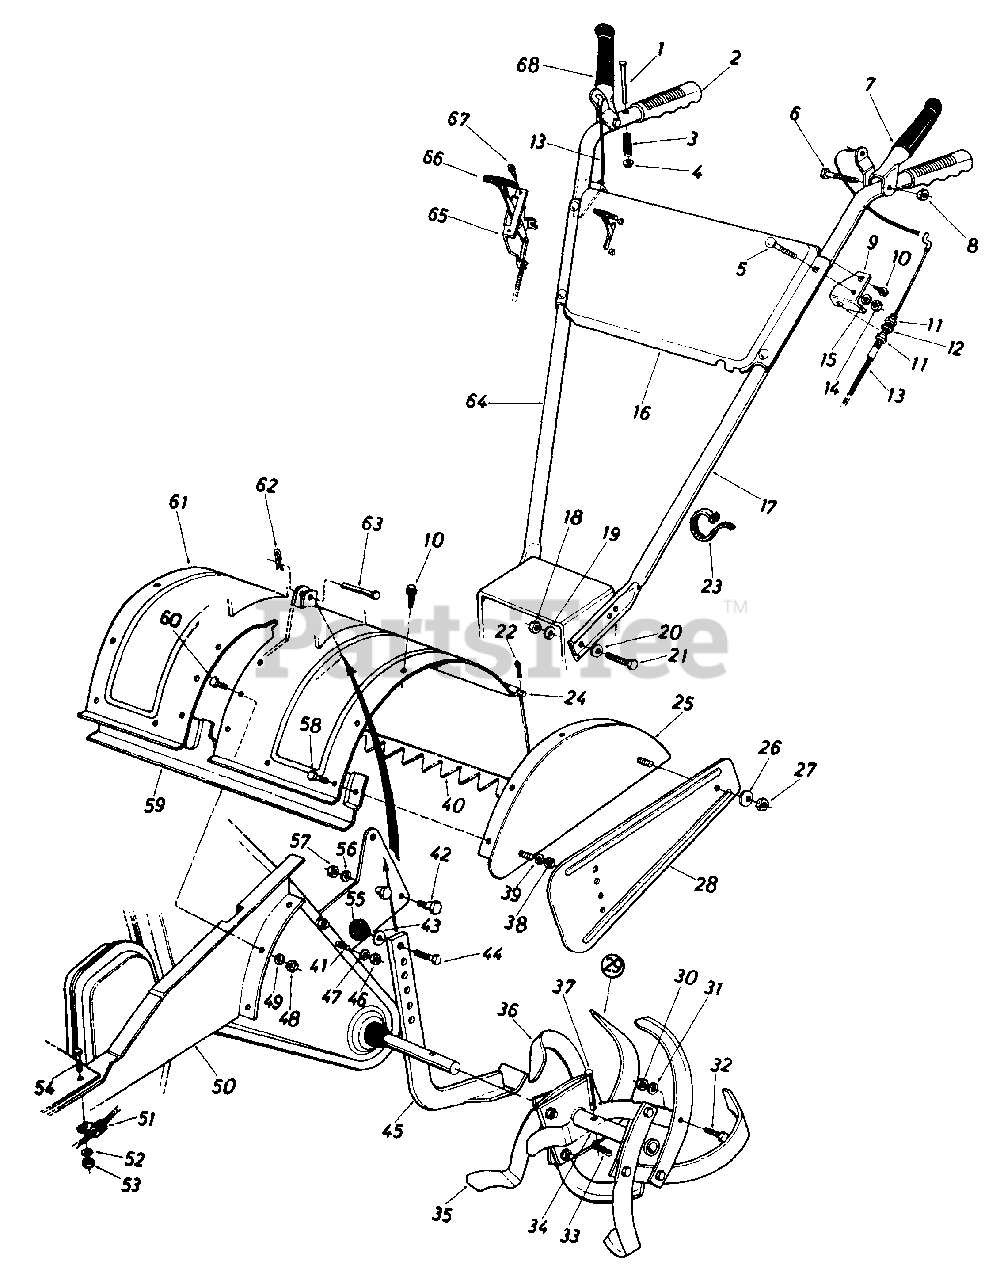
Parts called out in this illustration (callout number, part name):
1	Clevis Pin 1/4" Dia. x 2.25" Lg.
2	Grip
3	Compression Spring .33" O.D. x 1.2" Lg.
4	Cap Speed Nut 1/4" Rod
5	Carr. Bolt 5/16-18 x 1.75" Lg.
6	Hex Bolt 1/4-20 x 2.0" Lg.
7	Clutch Grip Ass'y. - L.H. (Tines)
8	Hex Cent. L-Nut 1/4-20 Thd.
9	Clutch Cable Bracket
10	Hex Wash. S-Tap Scr. 5/16-18 x .62" Lg.
11	Hex Nut 5/16-18 Thd.
12	L-Wash. 5/16" I.D.
13	Clutch Control Cable
14	Hex Nut 5/16-18 Thd.
15	L-Wash. 5/16" I.D.
16	Handle Panel
17	Handle Ass'y. - L.H.
18	Hex Nut 3/8-16 Thd.
19	L-Wash. 3/8" I.D.
20	Bell-Wash. 3/8" I.D.
21	Hex Bolt 3/8-16 x 1.00" Lg.
22	Cotter Pin 3/32" Dia. x 3/4" Lg.
23	Cable Tie
24	Tiller Flap Rod
27	Hex Nut 5/16-18 Thd.
31	L-Wash. 3/8" I.D.
32	Hex Bolt 3/8-24 x 1.25" Lg.
33	Hairpin Cotter
38	Hex Nut 5/16-18 Thd.
39	L-Wash. 5/16" I.D.
41	Hex Bolt 5/16-18 x 5/8" Lg.
42	Shld. Bolt 1/2" Dia. x .426" Lg.
43	Fl-Wash. 3/8" I.D. x 5/8" O.D. x .03
44	Hex Bolt 3/8-16 x 3/4" Lg.
46	Hex Nut 5/16-18 Thd.
47	L-Wash. 5/16" I.D.
48	Hex Nut 5/16-18 Thd.
49	L-Wash. 5/16" I.D.
52	L-Wash. 5/16" I.D.
53	Hex Nut 5/16-18 Thd.
54	Hex Bolt 5/16-18 x 3/4" Lg.
55	Ball Knob 1 1/4" Dia. x 3/8-16 Thd.
56	L-Wash. 3/8" I.D.
57	Hex Nut 3/8-16 Thd.
58	Hex Bolt 5/16-18 x .75" Lg.
61	Tine Shield Ass'y.
62	Hairpin Cotter
63	Clevis Pin 3/8" Dia.
64	Handle Ass'y. - R.H.
65	Throttle Control Ass'y.
66	Knob - Throttle Control
67	Hex Wash. Hd. Tap Scr. #8 x 5/8" Lg.
68	Clutch Grip Ass'y. - R.H. (Wheels)
